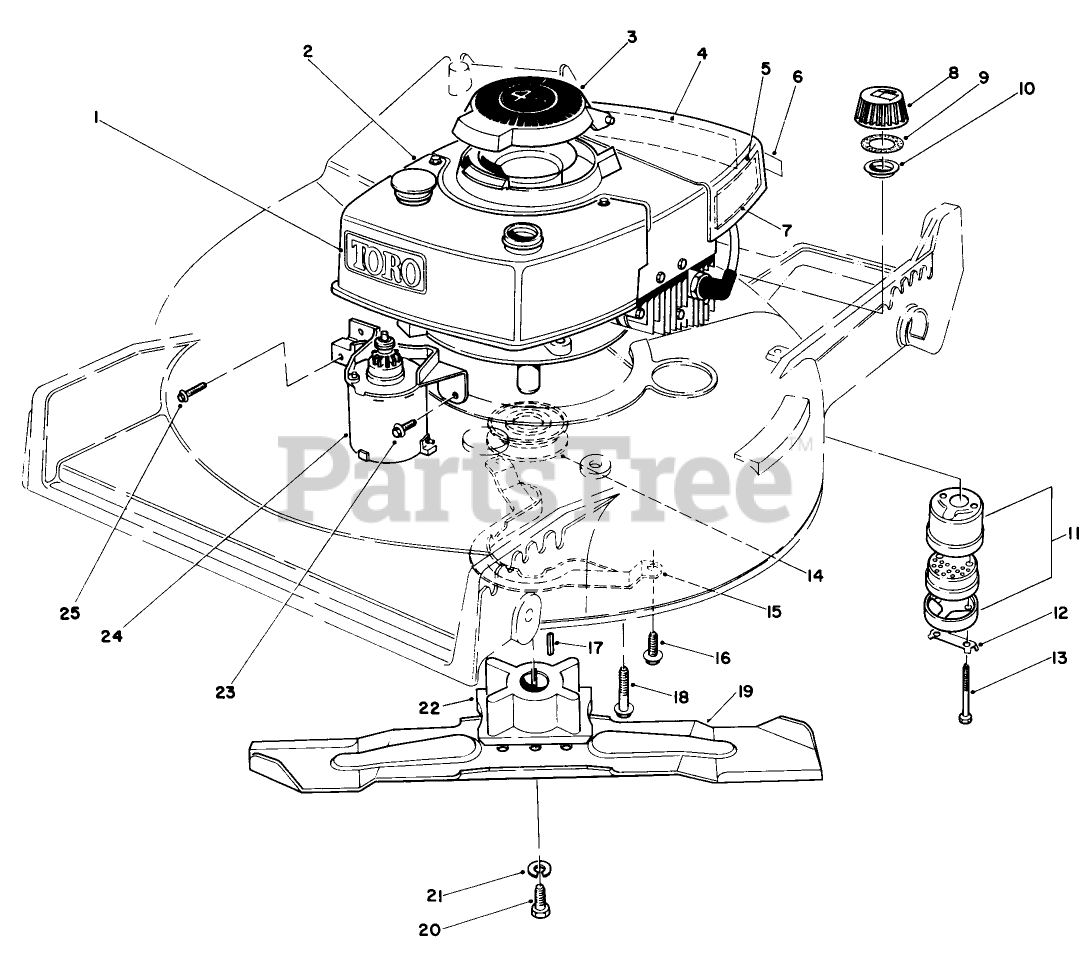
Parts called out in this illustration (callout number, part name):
2	Engine
3	Cover
7	Decal-Maintenance (German)
9	GASKET
11	MUFFLER ASM
12	CLIP - LOCKING
13	SCREW-HH
17	KEY-SQUARE
18	3/8-16 X 2 CAPSCREW
20	SCREW-BLADE
21	WASHER-LOCK
22	BLADE RETAINER(DEEP)
23	SCREW
